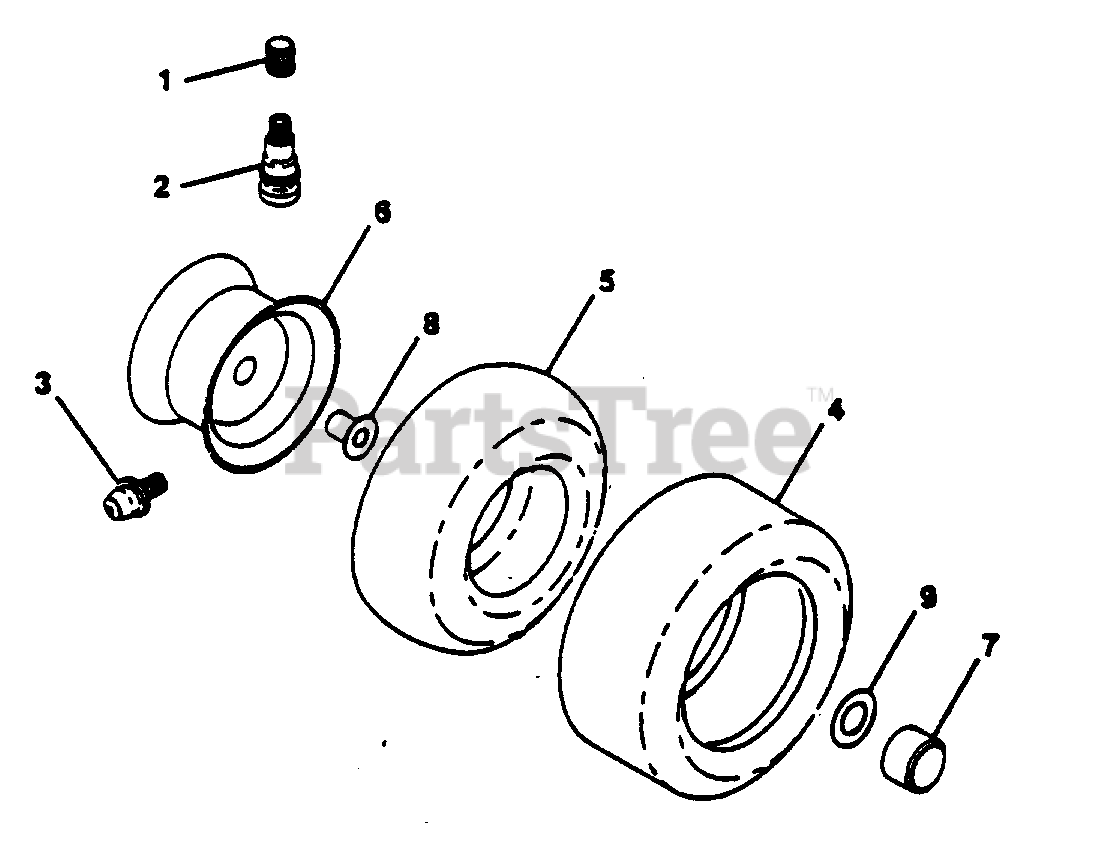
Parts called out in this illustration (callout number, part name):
1	Cap, Valve (AYP part number)
2	Stem, Valve (AYP part number)
3	Fitting, Grease (Front Wheels Only) (AYP part number)
4	Tire, Front (AYP part number)
4	Tire, Rear (AYP part number)
5	Tube, Front (Optional Service Items Only)
5	Tube, Rear (Optional Service Items Only) (AYP part number)
6	Rim, Front (AYP part number)
6	Rim, Rear
7	Cap Axle (AYP part number)
8	Bearing Flange (AYP part number)
9	Washer 25/32 x 1-5/8 x 16 Ga. (AYP part number)
